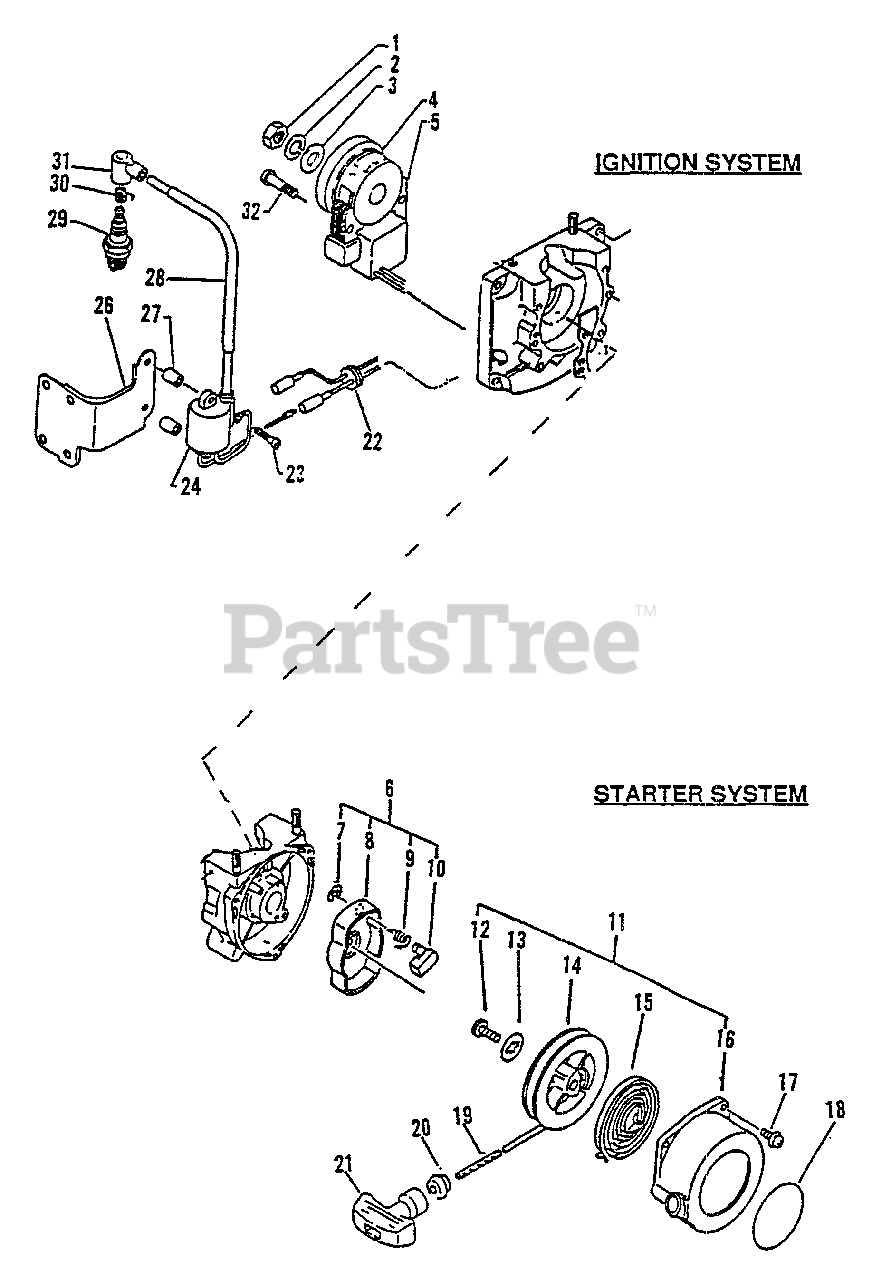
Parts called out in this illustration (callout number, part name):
2	WASHER, SPRING
4	FLYWHEEL
5	COIL, IGNITION
6	PAWL CATCHER ASSY
7	E-RING 4
8	CATCHER, PAWL
9	SPRING, RETURN
10	PAWL, STARTER
11	STARTER ASSY
14	REEL, ROPE
15	SPRING, RECOIL
16	CASE, STARTER
17	SCREW 5×18
19	ROPE, STARTER 4.0×880
20	GUIDE, ROPE
21	GRIP, STARTER
23	SCREW 4×25
24	COIL, IGNITION
28	TUBE, INSULATOR
29	SPARK PLUG - BM6A
30	TERMINAL, SPARK PLUG
31	CAP, SPARK PLUG
32	SCREW 5×25
